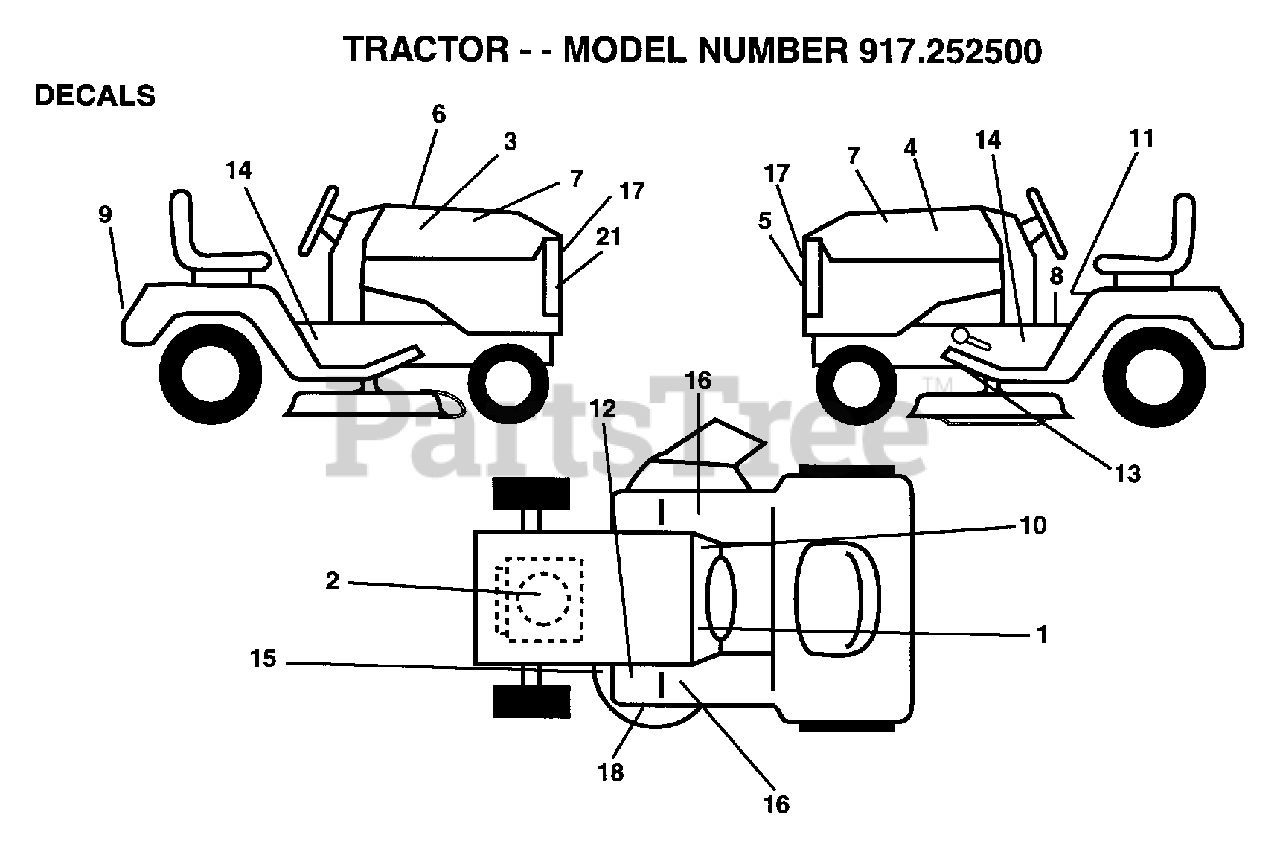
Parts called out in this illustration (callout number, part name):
1	DECAL.DASH.INST.
3	DECAL.HOOD.RH
4	DECAL.HOOD.LH
5	GRILL DECAL
6	DECAL
7	DECAL SIDE PN IC
8	DECAL BRAK PARK
9	"DECAL,FENDER"
13	DECAL.BELT-V.SCHM
14	CHASSIS DECAL
15	DECAL
17	DECAL.INS.HD.13HP
18	DECAL MWR QC SYS
21	DECAL LIGHTBOX
